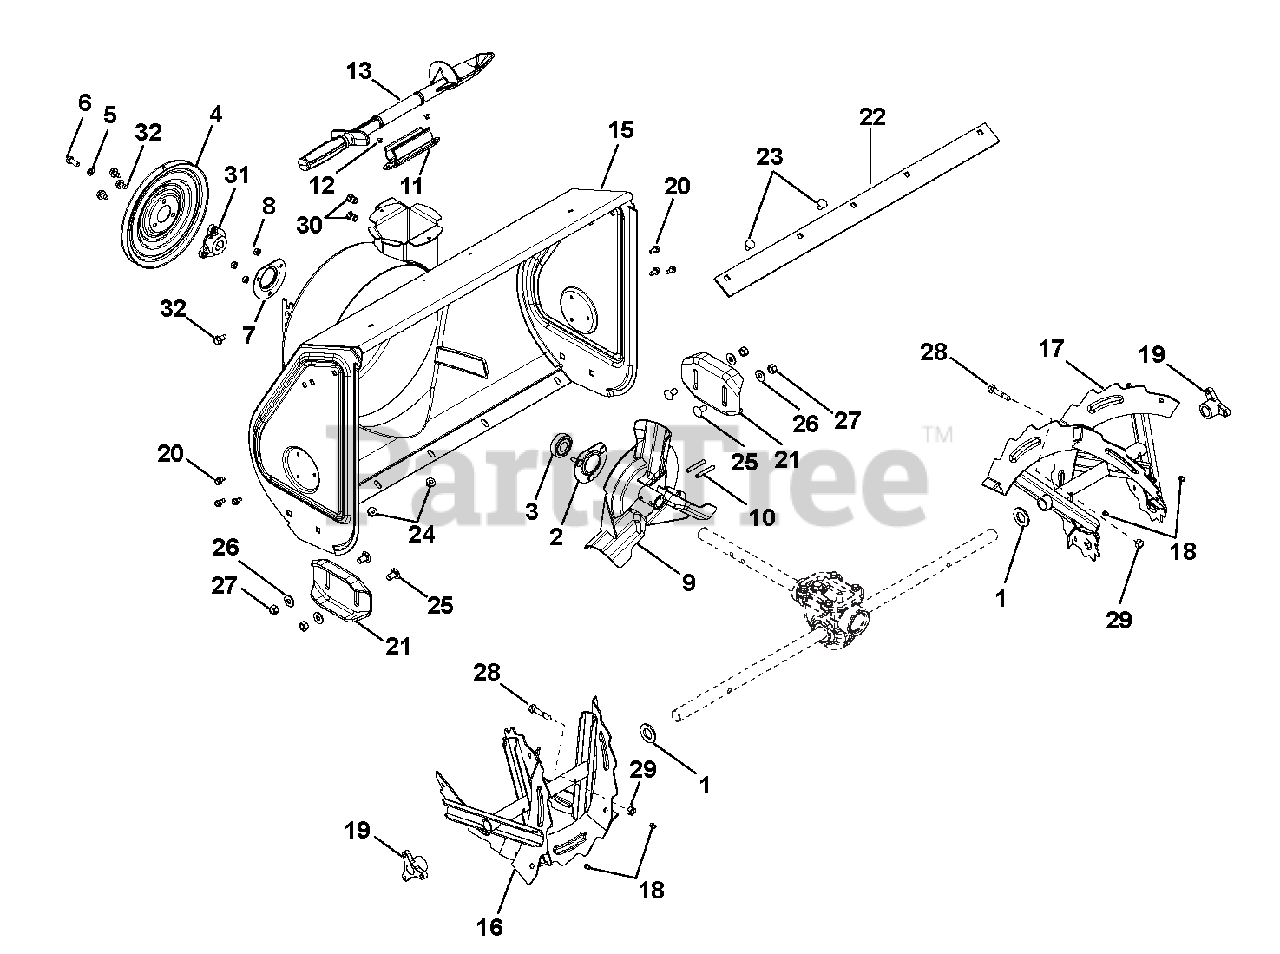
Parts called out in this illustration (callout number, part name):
1	@WSHR-FL-STL.812X1.50X.135YWZC
2	BEARING FLANGE
3	BRG-BALL .750X1.750X.50
4	PULLEY,SPIN FORM SINGLE GROOVE
5	WSHR-LK .312X.097 HVY YWZC
6	BLT-HEX .31-24X.75 YWZC GR5
7	BEARING FLANGE
8	@NUT-LK-CTR .25-20 YWZC
9	IMPELLER, COMPACT 12" 3-BLADE
10	PIN-ROLL .250X1.75
11	MOUNT, SNOW CLEAN OUT
12	RVT-POP .187 YZ
13	DEVICE, SNOW CLEAN OUT
15	BLOWER HOUSING, 24"
15	BLOWER HOUSING, 28"
16	RAKE, 24" RH, BLK SERR W/ZERK
16	RAKE, 28" RH, BLK SERR W/ZERK
17	RAKE, 24" LH, BLK SERR W/ZERK
17	RAKE, 28" LH, BLK SERR W/ZERK
18	ZERK,FITTING .25X.125 DRIVE IN
19	BUSHING, RAKE SHAFT .75"
20	SCR-TAP .25-20X.50 HWH TR YWZ
21	SKID SHOE, REVERSIBLE - BLACK
22	SCRAPER BLADE, 28" COMPACT HI
22	SCRAPER BLADE, 24" COMPACT HI
23	BLT,RDSHHDSQSHNK .31-18X.62 YZ
24	@NUT-LK-TOP-FLG .31-18 YWZC
25	@BLT-RHDSSQNK .38-16X.75 G5YZ
26	@WSHR-FL-STL.38X.875X.083 YWZC
27	@NUT-LK-CTR .38-16 YWZC
28	SHEAR BOLT WITH NUT
29	@NUT-LK-CTR .25-20 YWZC
30	NUT, THREADED INSERT .38-16
31	PULLEY HUB, BOLT-ON D-BORE .75
32	@SCR-TAP .31-18X.50 HWH TR YWZ
